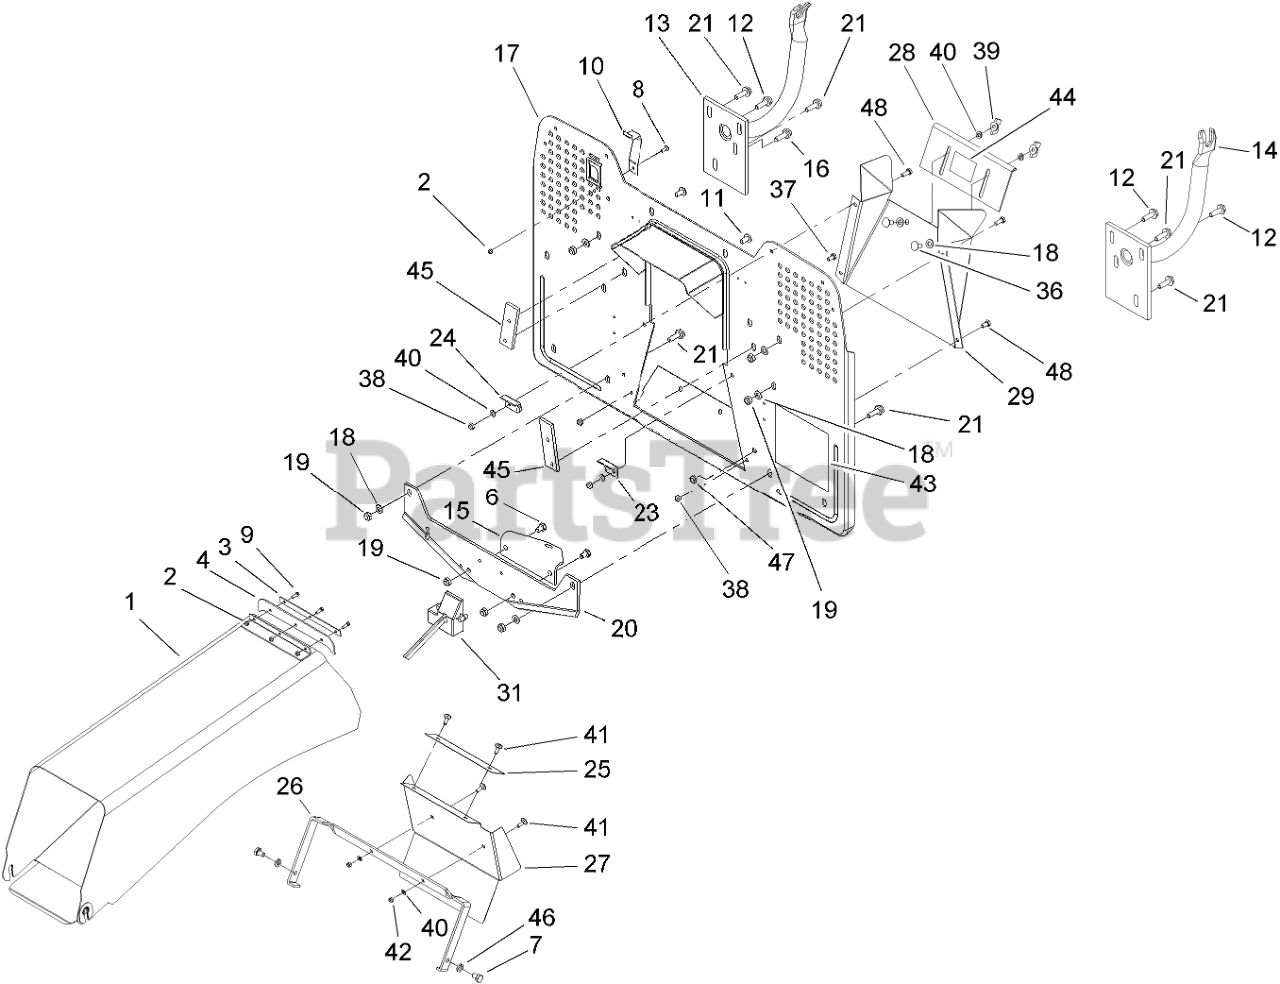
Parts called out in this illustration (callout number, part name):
1	Tunnel
2	NUT-HEX
3	PLATE-SUPPORT
4	SEAL-RUBBER
6	SCREW-HH
7	SCREW-HHF
9	SCREW-SFH
10	COVER-SWITCH
11	BOLT-CARRIAGE
13	SUPPORT-COLLECTOR, RIGHT
14	SUPPORT-COLLECTOR, LEFT
15	HITCH-TOW
16	SCREW-HEX
17	COLLECTOR PLATE ASM
18	WASHER-FLAT
19	NUT-LOCK, NI
20	SUPPORT-HITCH, TOW
21	SCREW-HEX
23	Support-Tunnel, Left
24	Support-Tunnel, Right
25	Shield-Rubber
26	BRACKET-SHIELD, PROTECTIVE
27	SHIELD-PROTECTIVE
28	Shield-Adjustable
29	Hopper-Receiving
37	SCREW-HH
38	NUT-LOCK
39	NUT-WING
40	WASHER-FLAT
41	BOLT-CARRIAGE
42	NUT-LOCK
43	DECAL-BYPASS, HYDRO
44	DECAL-POSITION, BAGGING
45	Plate-Reinforcing
46	Washer-Spring
47	Bushing
48	Screw-HH
